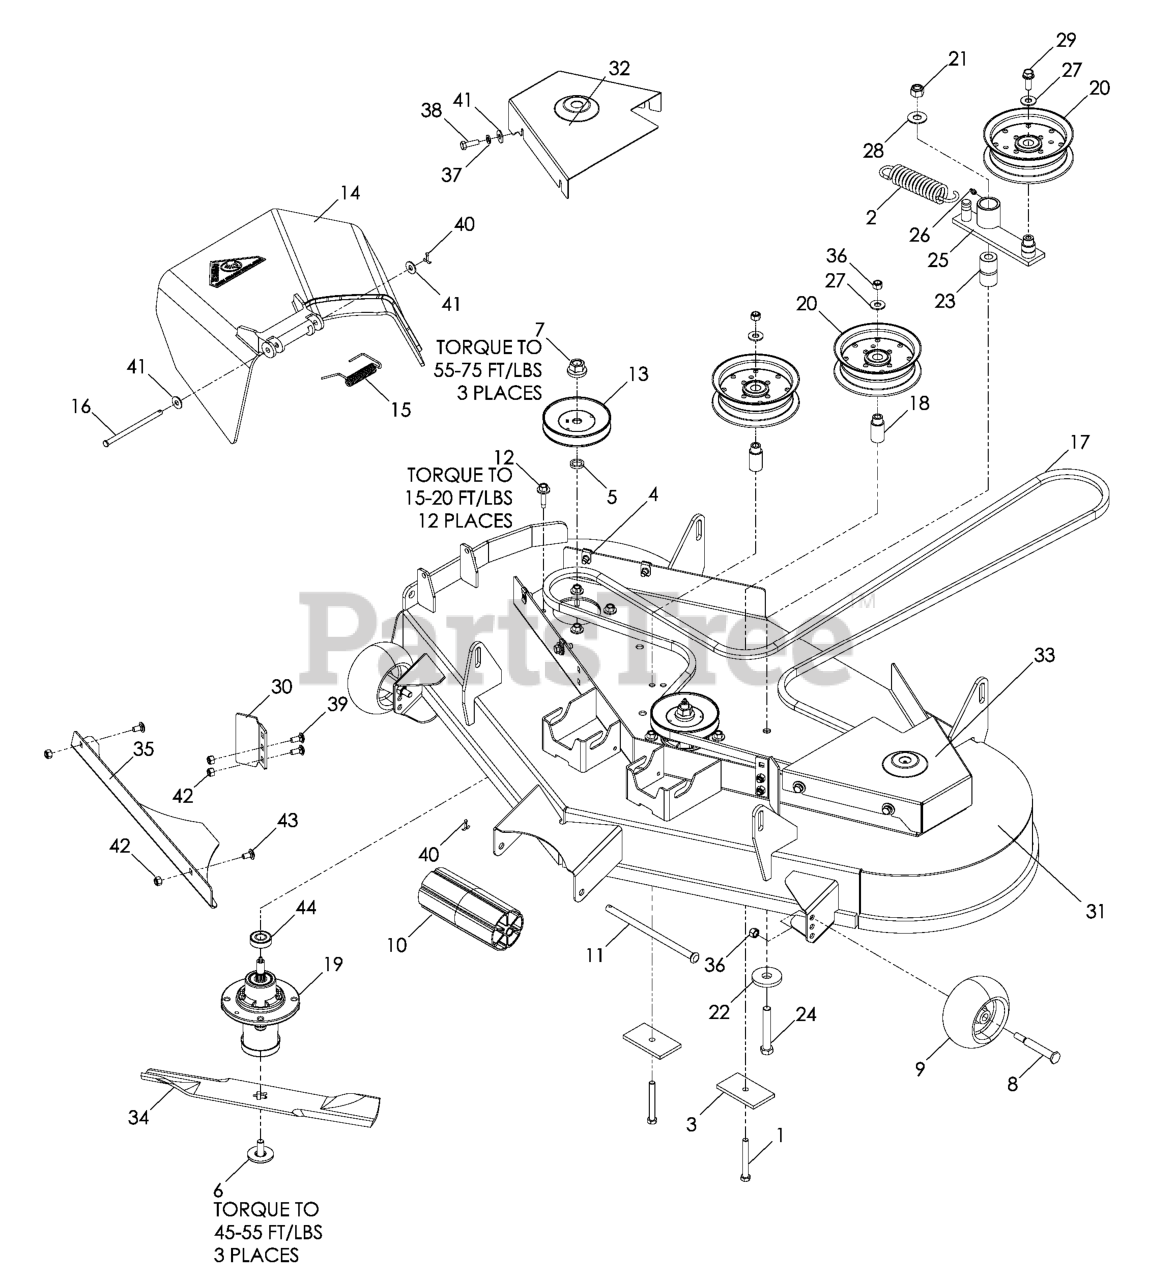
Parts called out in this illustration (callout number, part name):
1	HCS 3/8C X 3
3	SUPPORT PLATE
4	U-CLIP 5/16-18 NUT RETAINER
5	WASHER-SPACER
6	BLADE BOLT ASSY-7/16" TB REPL
7	LOCKNUT - 9/16
8	SHOULDER BOLT 1/2X2-5/8 ZD SPE
9	GAUGE WHEEL
10	NOSE ROLLER 48"
11	NOSE ROLLER ROD
12	WASHER HEAD SCREW
13	PULLEY MANDREL
14	DISCHARGE CHUTE 48"
15	SPRING - TORSION
16	PIN-CLEVIS 5/16 DIA X 5.19 ZD
17	DECK BELT
18	IDLER BUSHING
19	MANDREL.DECK.ASSEMBLY
20	PULLEY, IDLER
21	NUT 1/2-13 HEX NYLOC ZD
22	WASHER, SUPPORT
23	PIVOT BUSHING
24	HCS 1/2C X 3 1/4
26	ZERK
27	WASHER 3/8 FLAT
28	WASHER 1/2 FLAT
29	4CS 3/8C X 1 SERRATED HEAD
31	DECK W/DECALS 48"
32	BELT SHIELD W/DECALS 48 RT
33	BELT SHIELD W/DECALS 48 LT
34	BLADE, 16-1/4"
35	CONFINEMENT PLATE 48" BLK
36	NUT 3/8-16 NYLOC
37	WASHER.LOCK.HVY.HLCL.SPR.5/16
38	HCS 5/16C X 1
39	BOLT 5/16C X 3/4" CARRIAGE
40	RP_COTTER PIN 1/8 X 3/4
41	WASHER 5/16 FLAT
42	NUT 5/16 NYLOC
43	CARRIAGE BOLT 5/16C X 5/8"
44	BEARING, BALL
